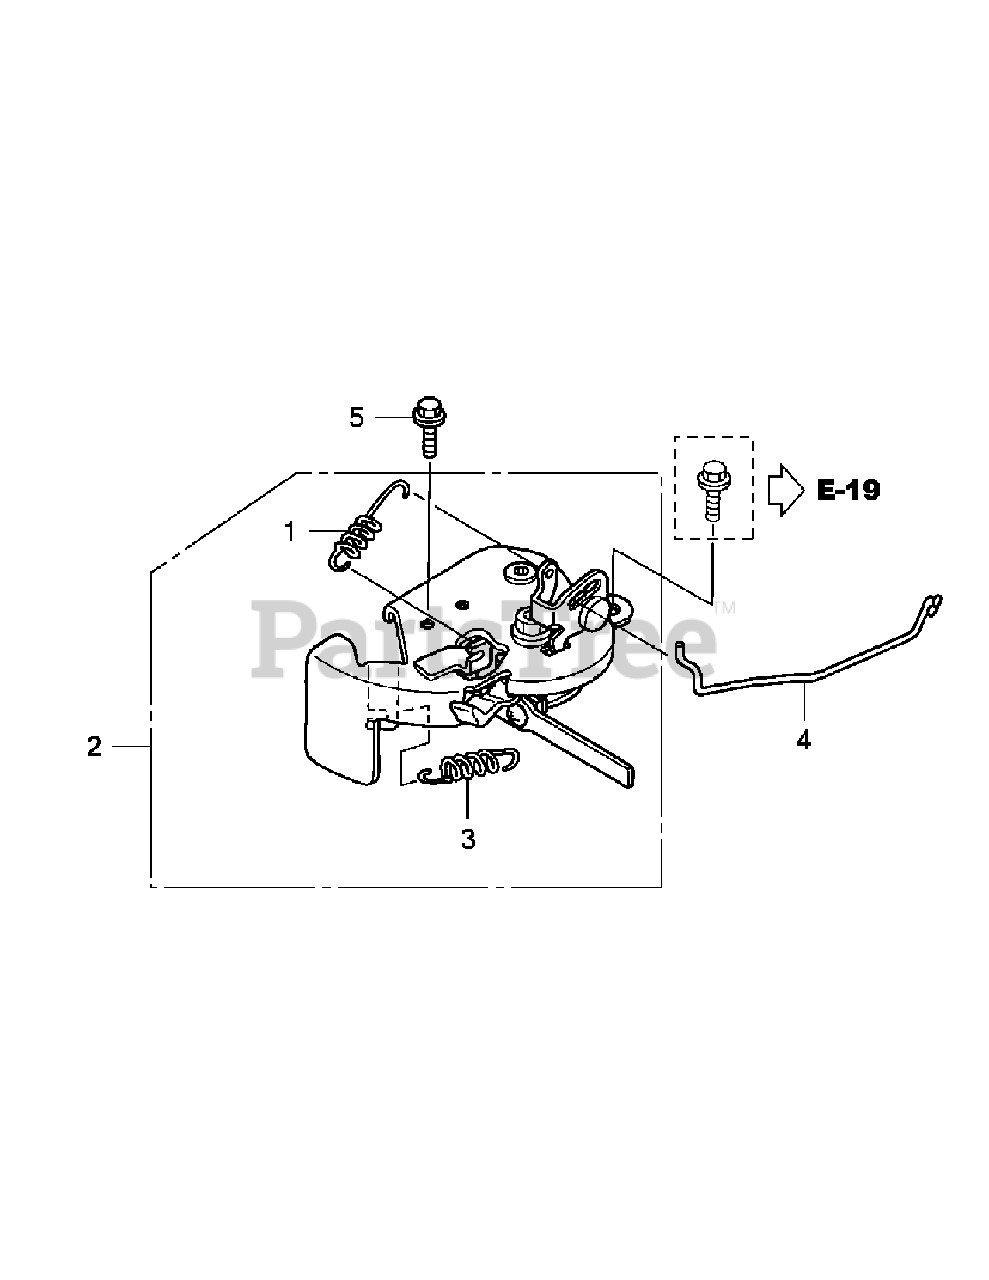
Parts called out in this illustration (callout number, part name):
1	SPRING, RETURN
2	LEVER ASSY., CHOKE
3	SPRING, CHOKE LEVER
4	ROD, STOP
5	BOLT, FLANGE, 6X20(CT200)
